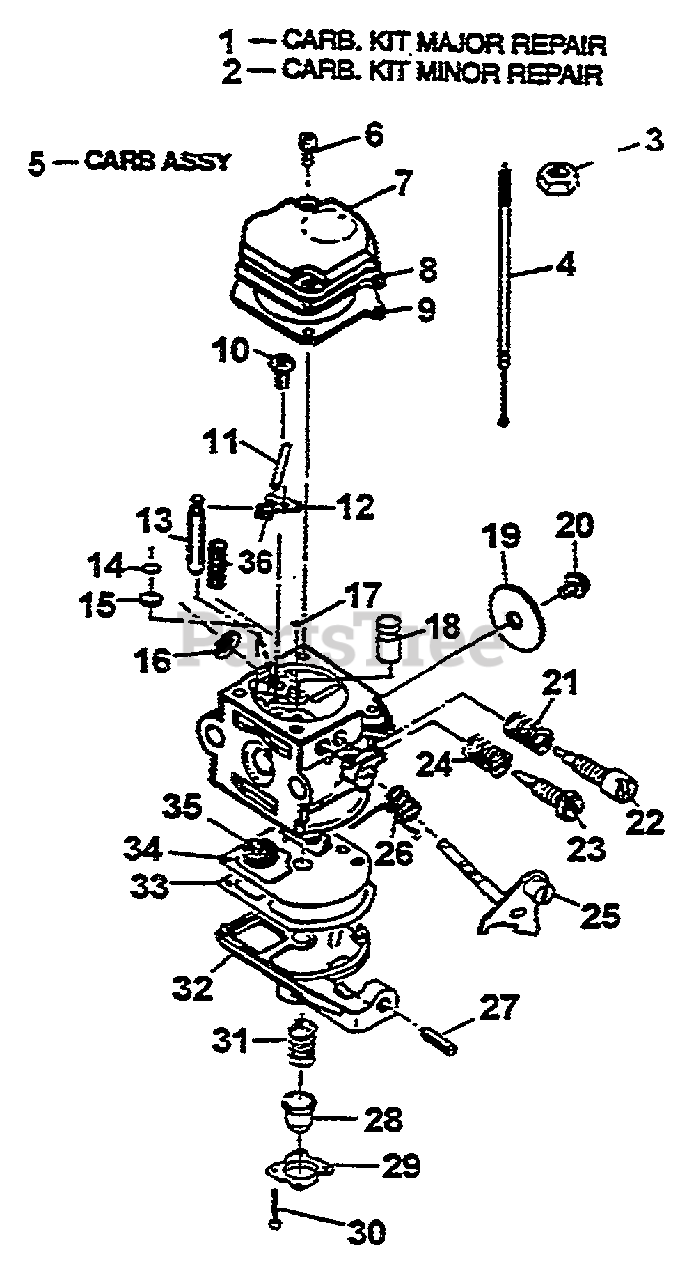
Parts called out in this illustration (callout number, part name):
1	CARB KIT
2	DIAPHRAGM KIT
4	THROTTLE CABLE
5	CARB ASSY.
6	SCREW
7	CAP-MAIN
8	DIAPHRAGM
9	GASKET
12	ARM, NEEDLE
13	NEEDLE
15	CHECK VALVE
17	WELCH PLUG
18	NOZZLE ASSY
19	THROTTLE VALVE
22	NEEDLE, LOW SPEED
23	NEEDLE HIGH SPEED
27	SCREW, IDLE
28	PRIMER BULB
29	COVER, PUMP
31	SPRING
32	COVER, FUEL PUMP
33	GASKET, PUMP
34	DIAPH. PUMP
35	STRAINER
36	SPRING
